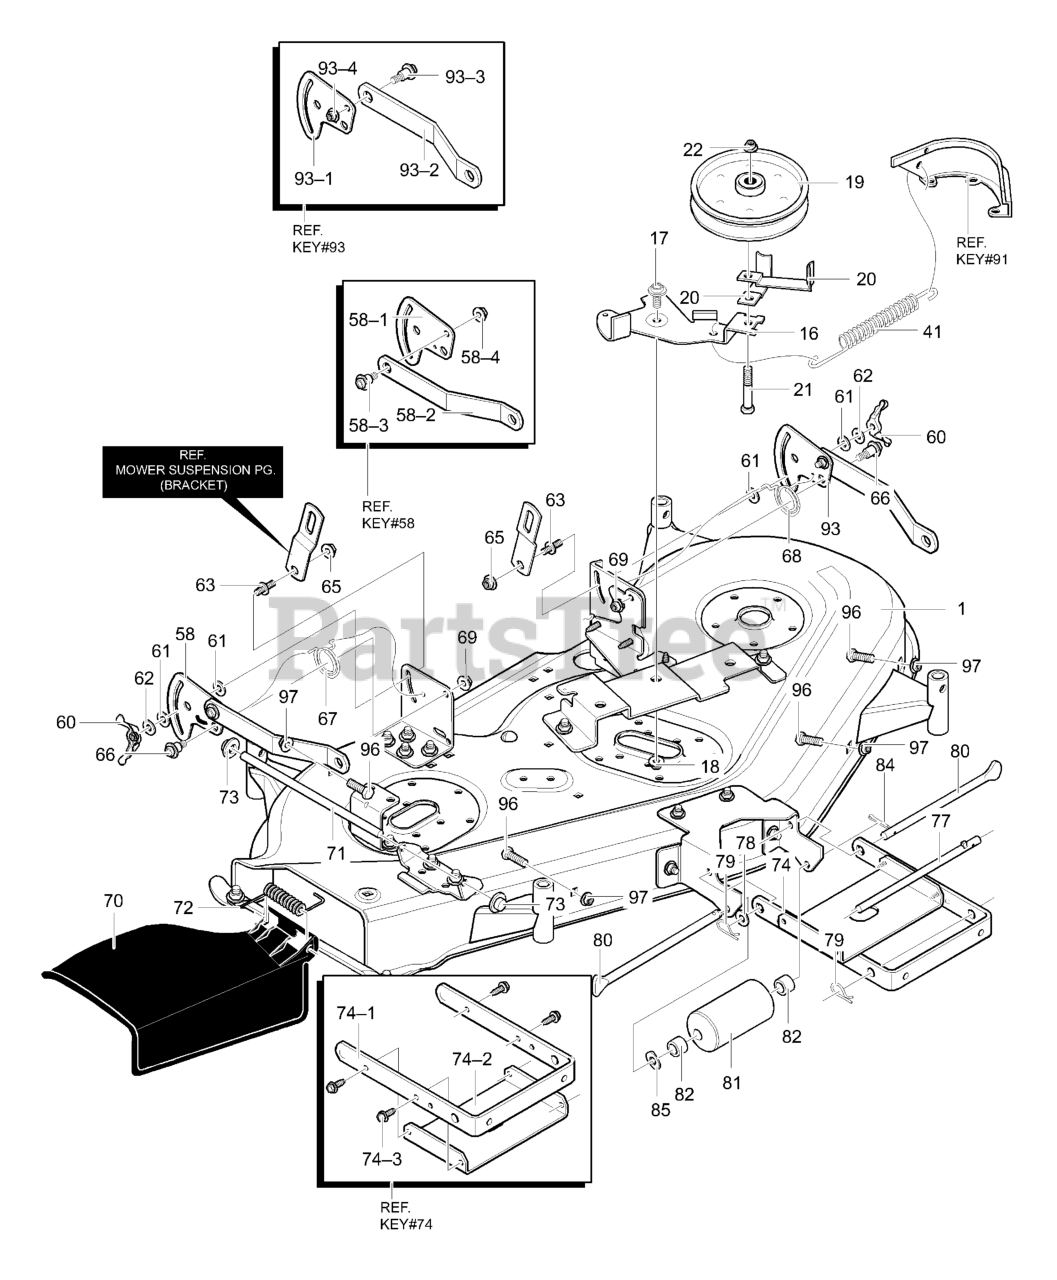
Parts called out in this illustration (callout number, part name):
1	DECK, MOWER
16	ARM, IDLER
19	IDLER PULLEY
20	SPRING - BELT GUIDE
41	SPRING, EXTENSION
58	PLATE, RIGHT REAR SUSP.
58-1	PLATE, SUSPENSION
58-2	BRACKET, SUSPENSION
58-3	BOLT, SHOULDER
58-4	NUT
60	WINGNUT
61	PAD, FRICTION
62	WASHER
63	PIN, HANGER
66	BOLT, SHOULDER
67	SPRING, TORSION
68	SPRING, TORSION
70	DEFLECTOR, CHUTE
71	ROD, DEFLECTOR
72	SPRING, TORSION
73	NUT, PUSH CAP
74	BRACKET AND STIFFENER
74-1	BRACKET, STIFFENER
74-2	STIFFENER
77	ROD, HANGER
78	WASHER, FLAT
79	PIN, HAIR
80	ROD, ROLLER
84	PIN, COTTER
85	WASHER, WAVE
93	PLATE, LEFT REAR SUSP.
93-1	PLATE, SUSPENSION
93-2	BRACKET, SUSPENSION
93-3	BOLT, SHOULDER
93-4	NUT
